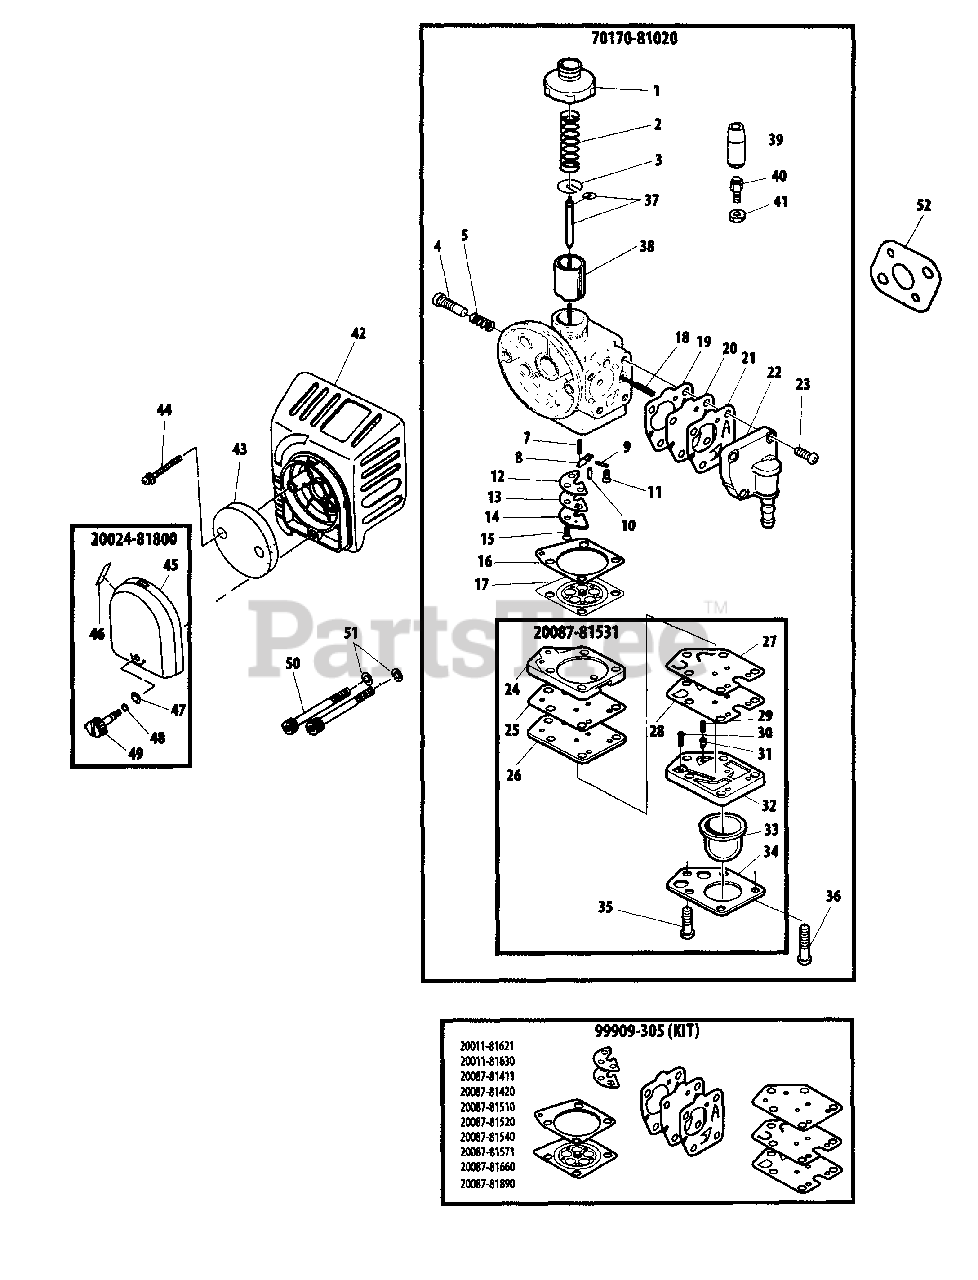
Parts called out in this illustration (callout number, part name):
1	CAP, CARBURETOR
2	SPRING
3	WASHER, SPRING SUPPORT
4	SCREW, IDLE ADJUST
5	SPRING
8	LEVER, METERING
9	PIN, METERING LEVER
10	VALVE, INLET NEEDLE
11	SCREW M3×8
12	GASKET
13	VALVE, CHECK
14	PLATE
15	SCREW M3×8
16	GASKET, METERING DIAPHRAGM
17	DIAPHRAGM, METERING
18	SPRING, COIL
19	GASKET, DIAPHRAGM
20	DIAPHRAGM, METERING
21	VALVE, PUMP
22	PUMP BODY
23	SCREW
24	COVER, PUMP
25	GASKET
26	PLATE, PUMP
27	VALVE, CHECK
28	GASKET
29	SPRING
30	SPRING
31	VALVE, CHECK
32	COVER, PUMP
33	BULB, PURGE
34	RETAINER, PURGE BULB
35	SCREW
36	SCREW 3×20
37	NEEDLE, JET
38	SLIDE VALVE
39	GROMMET
40	ADJUSTER, CABLE
41	NUT, LOCK
42	CASE, AIR FILTER
43	FILTER, AIR
44	SCREW
45	COVER, AIR FILTER
46	LABEL, CHOKE
47	WASHER, CONE M6
48	O-RING
49	THUMBSCREW
50	BOLT M5×65
51	LOCKWASHER
52	GASKET, INTAKE
